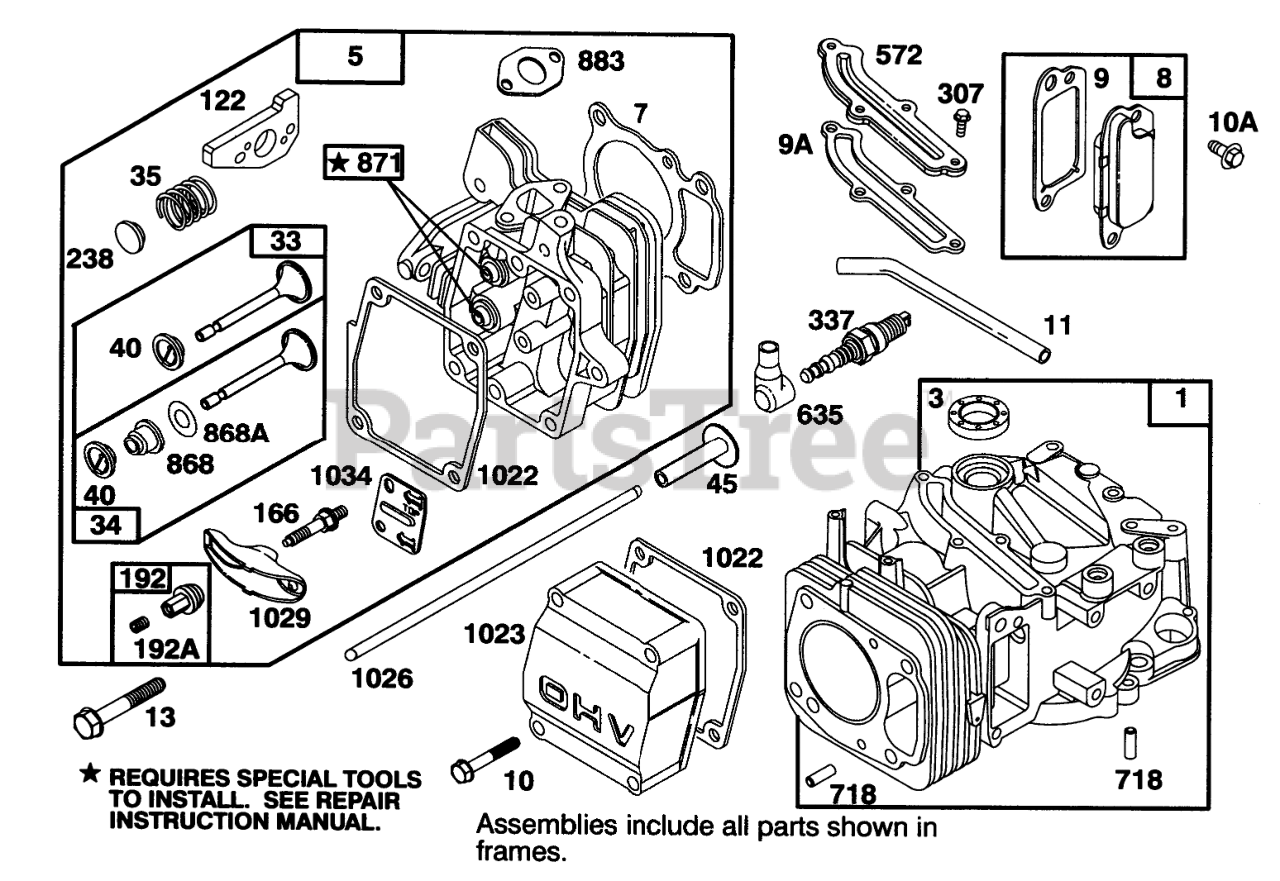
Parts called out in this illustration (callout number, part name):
1	CYLINDER ASSEMBLY
3	SEAL - OIL
5	CYLINDER HEAD
7	CYLINDER HEAD GASKET
8	Breather Assy
9	BREATHER GASKET
9A	GASKET-BREATHER
10	HEX HEAD SCREW
10A	HEX HEAD SCREW
11	TUBE - BREATHER
13	CYLINDER HEAD SCREW
33	EXHAUST VALVE
34	INTAKE VALVE
35	VALVE SPRING
40	SPRING RETAINER
45	VALVE TAPPET
122	ADAPTER ASSEMBLY
166	ROCKER ARM STUD
192	NUT - HEX SPECIAL
192A	SCREW SET
238	VALVE CAP
307	SCREW - SEM
337	PLUG-SPARK
572	BAFFLE - CYCLINDER
635	SPARK PLUG ELBOW
718	DOWEL - SLEEVE
868	SealAssy-Valve
868A	Seal-Valve
871	Bushing-Guide
883	EXHAUST GASKET
1022	ROCKER COVER GASKET
1023	COVER - VALVE
1026	PUSH ROD
1029	ROCKER ARM
1034	PUSH ROD GUIDE
